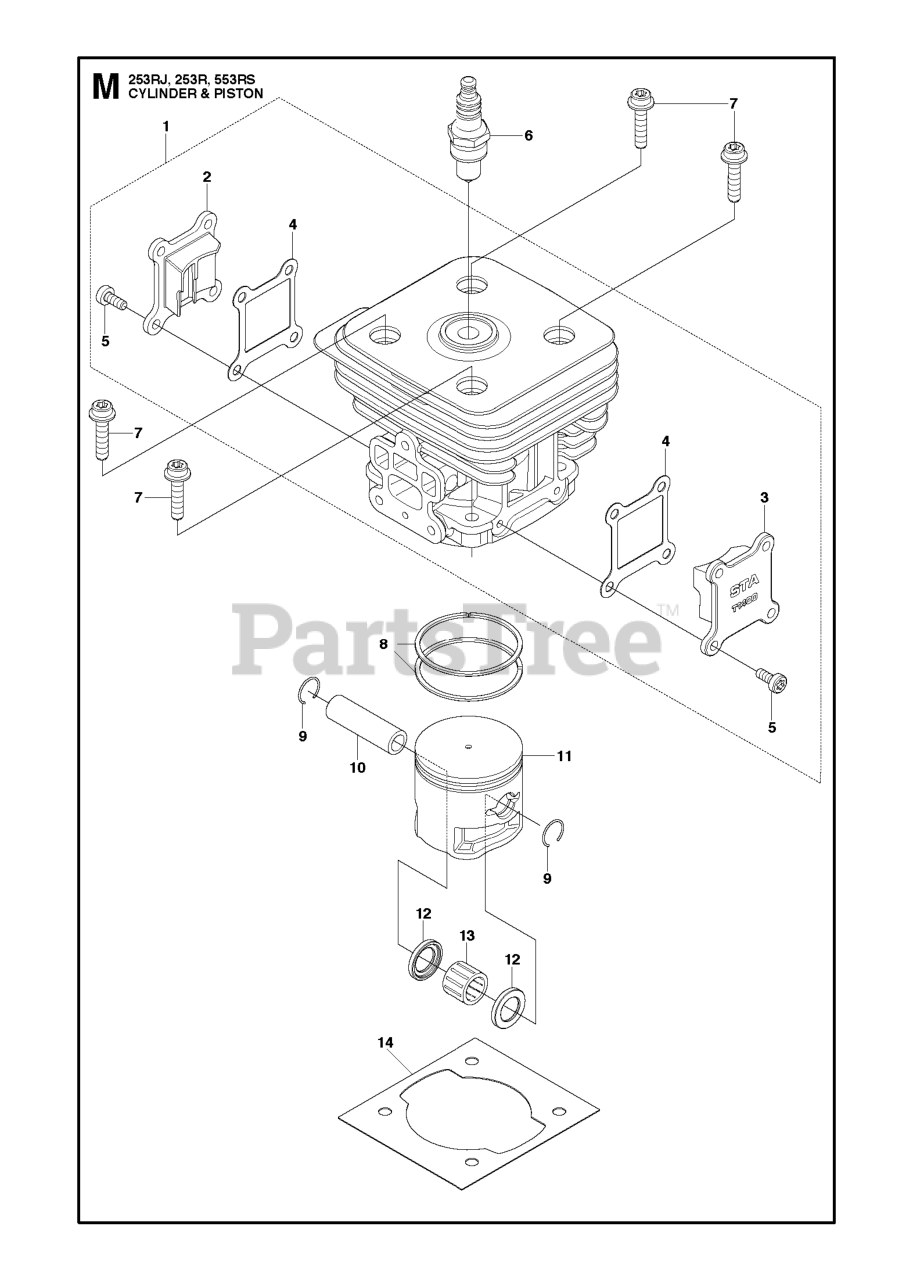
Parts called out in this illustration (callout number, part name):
4	GASKET, TR
6	PLUG CMR7H
8	RING
10	PISTON PIN
13	BEARING
